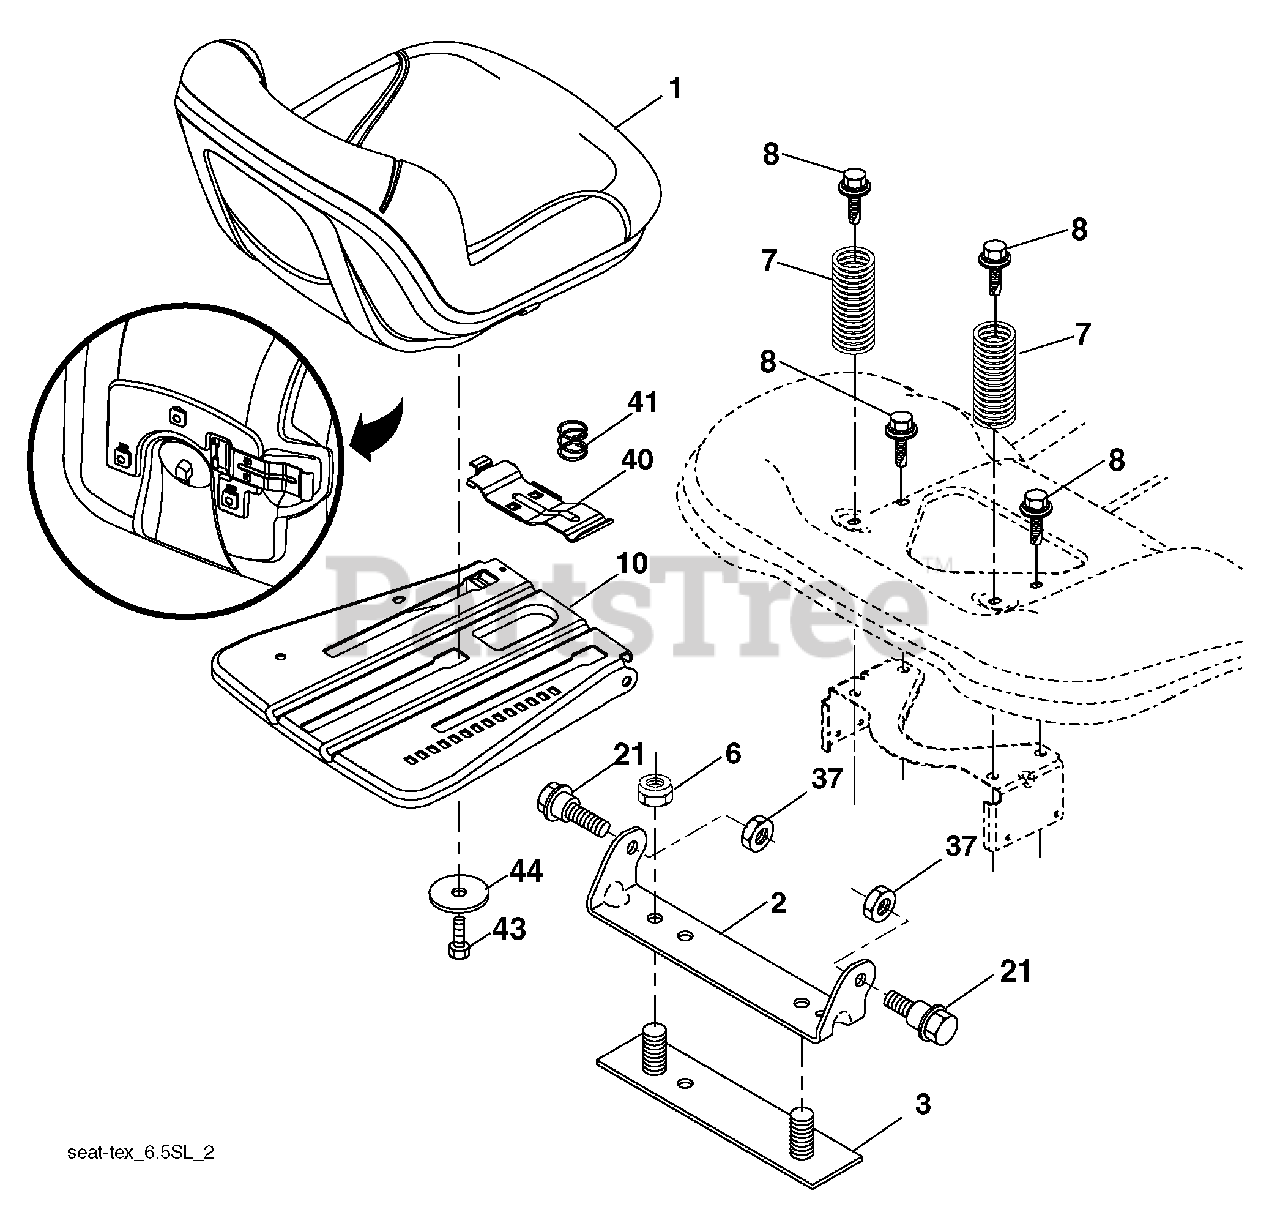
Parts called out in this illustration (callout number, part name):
1	Seat
2	Bracket Pivot Fender
3	Strap, Asm Fender
6	Nut, Lock w/Ins. 3/8-16 unc
7	Spring, Seat Cprsn
8	Bolt 5/16-18 unc x 3/4 w/Sems
10	Pan, Seat
21	Bolt, Shoulder 5/16-18
37	Nut, Lock 5/16-18 unc
40	Handle Slide Seat
41	Spring Latch Seat
43	Bolt Fin Hex 3/8-16 unc x 3/4
44	Washer 13/32 x 2-3/8 x 12 Ga.
